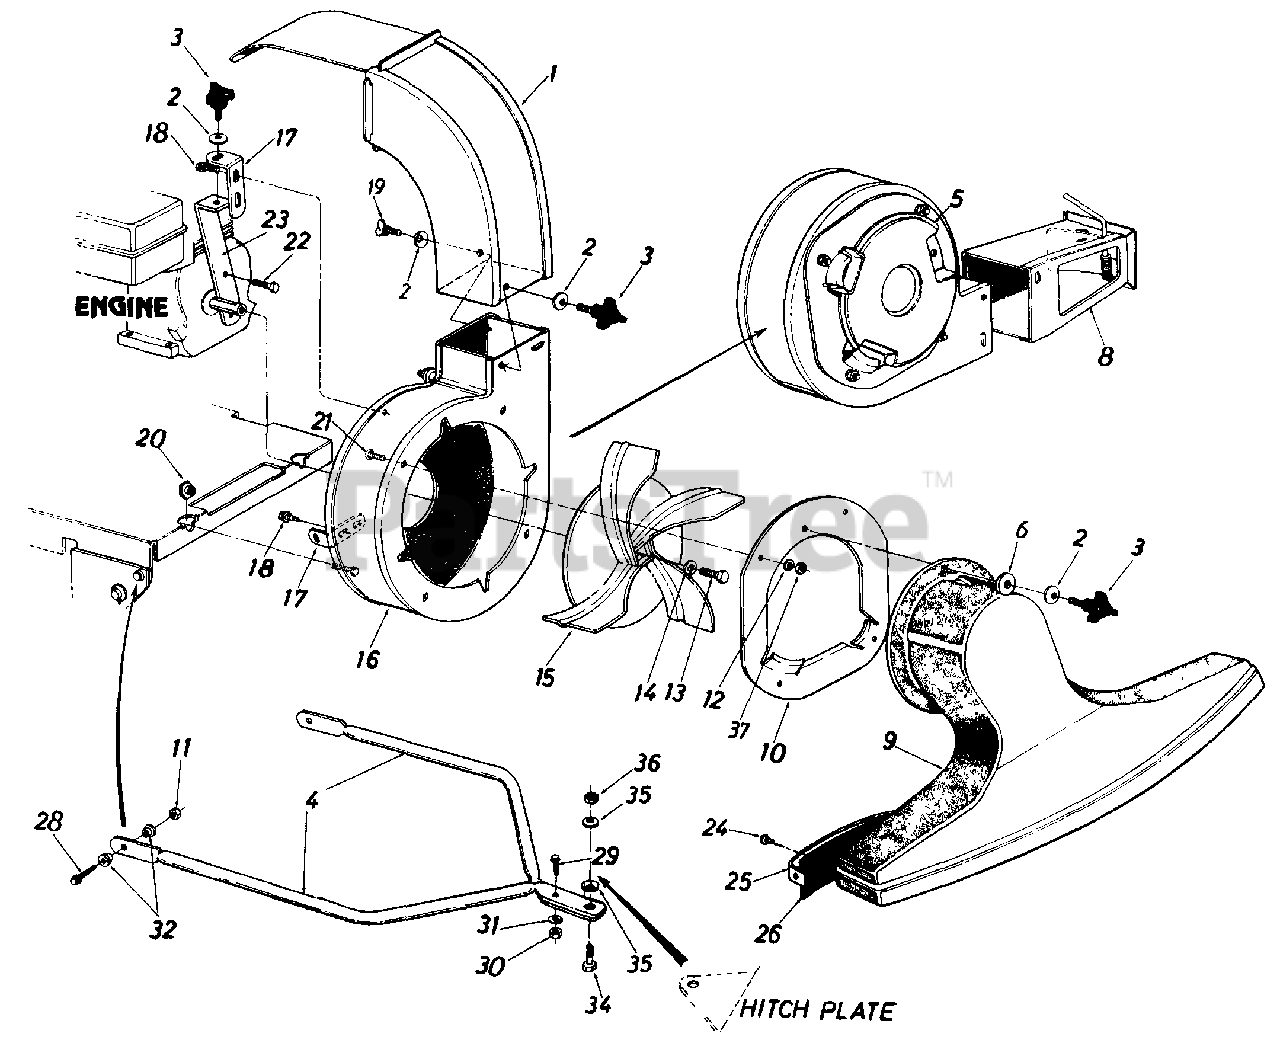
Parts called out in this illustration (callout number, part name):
3	Hand Knob
6	Fl-Wash .344" I.D. x 1.125" O.D.
12	L-Wash. 5/16" I.D.
13	Hex Bolt 3/8-24 x 1.25" Lg.
14	L-Wash. 3/8" I.D. H.D.
19	Thumb Screw 5/16-18
20	Hex Shoulder Nut .50 I.D.
21	Carriage Bolt 5/16-18 x .62"
22	Hex Locking Bolt 5/16-24 x .75" Lg.
28	Hex Bolt 5/16-18 x 1.00" Lg.
29	Truss Mach. Scr. 1/4-20 x .75"
30	Hex Nut 1/4-20 Thd.
31	L-Wash. 1/4" I.D.
32	Shoulder Spacer
34	Shld. Bolt .496 Dia.
35	Belleville Wash .39" I.D. x 1.12" 0 D
36	Hex Jam L-Nut 3/8-26 Thd.
37	Hex Nut 5/16-18 Thd. (Gr. 5)
